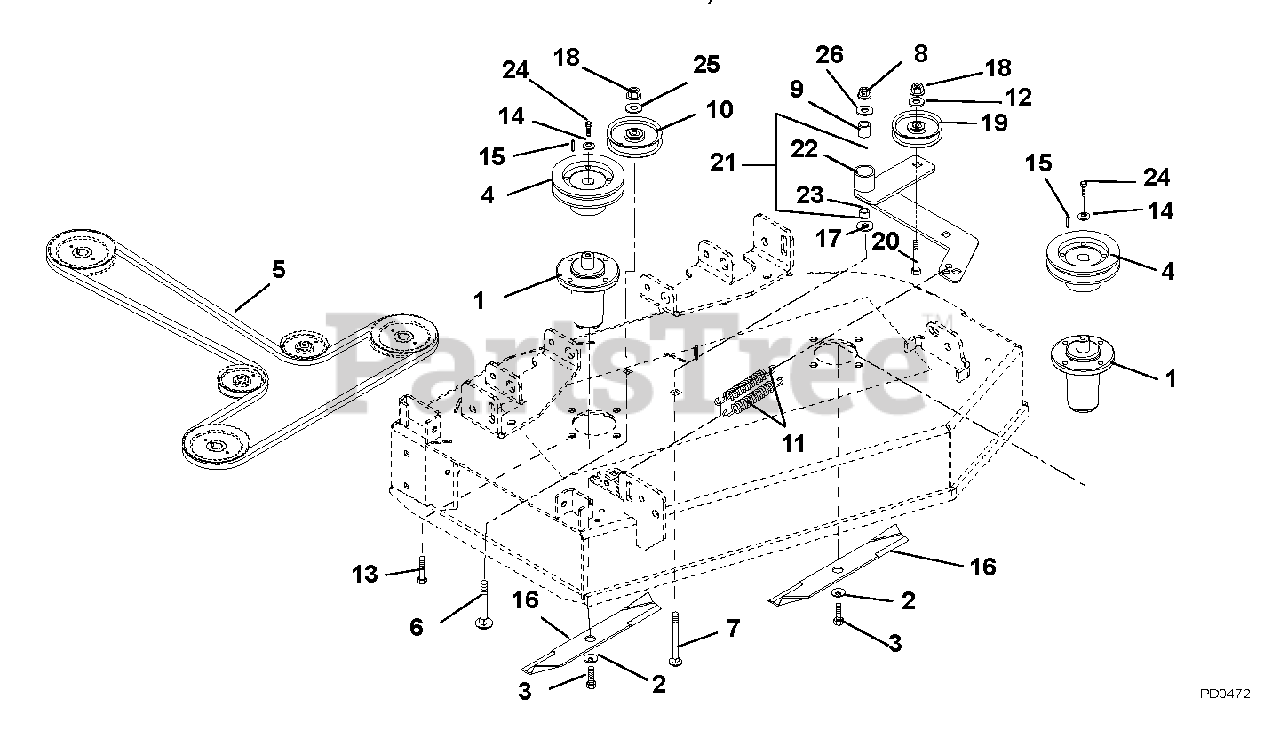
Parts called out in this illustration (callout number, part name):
1	Assembly, Spindle Short
2	Washer, Bellville .63 x 1.625 x .14
3	Bolt, Hex .62-18 x 1.75 Grade 8
4	Sheave, 5.00 Spindle
5	V-Belt, B-Section 49.68 x .62548.80 x .625
6	Bolt, Round Head Square Neck .38-16 x 3.0 Grade 5
7	Bolt, Round Head Square Neck .50-13 x 3.50 Grade 5
8	Nut, Nyloc Flange .50-13
9	Bushing, Spacer .505/.500 x .999/.996 x 2.05/2.03
10	Idler, Flat 4.00 x .38
11	Spring, Extension
12	Washer, Flat Steel .375 x 1.125 x .065
13	Bolt, Hex .38-16 x 1.00 EP30
14	Retainer, Sheave
15	Key, Square .25 x .25 x .875
16	Blade, 50" mower Hi-Lift
17	Washer, Flat Steel .531 x 1.250 x .100
18	Nut, Nyloc Flange 3/8-16
19	Idler, Flat 4.00 x .38
20	Bolt, Round Head Square Neck .38-16 x 2.00 Grade 5
21	Assembly, Idler Pivot Arm
22	Weldment, Idler Pivot Arm
23	Bushing, 1.00 x 1.125 x 1.936
24	Bolt, Hex .38-16 x 2.75 Grade 8
25	Seal, Idler Bearing
26	Washer, Flat Steel 511 x 1.441 x .125
